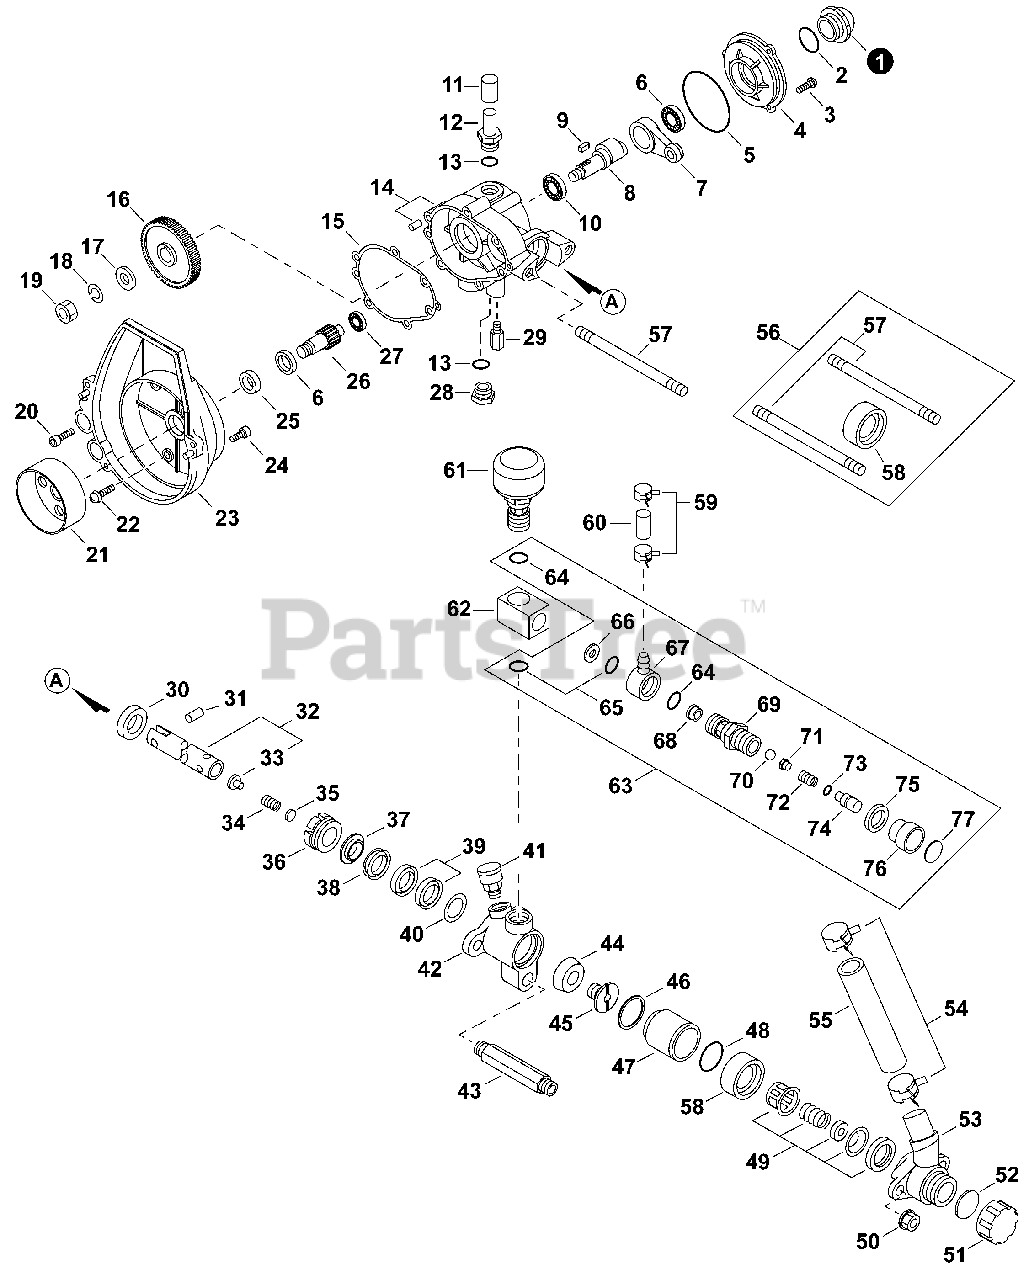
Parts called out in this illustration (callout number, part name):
1	GAUGE, OIL
3	SCREW 4x12
4	COVER, PUMP
6	BEARING, BALL 6001
7	ROD, CONNECTING
8	CRANKSHAFT
10	BEARING, BALL 6201
12	BOLT, OIL
14	CASE KIT, PUMP
15	GASKET, PUMP
16	GEAR, SPUR
17	WASHER 8.5x16x1.2
18	WASHER, SPRING 8
20	BOLT 5x25
21	DRUM, CLUTCH
22	SCREW 5x25
23	COVER, FAN
24	BOLT 5x18
25	SEAL, OIL
26	SHAFT, PINION
27	BEARING, BALL 609
28	CAP, DRAIN
30	SEAL, OIL
31	PIN, PISTON
32	PLUNGER SET, W/SPRING HOLDER
33	HOLDER, SPRING
34	SPRING, VALVE
38	PACKING, GREASE
39	PACKING SET
41	CUP ASSY, GREASE
42	CYLINDER
43	CONNECTOR, HOSE
44	PACKING, PISTON
45	SEAT, VALVE
49	VALVE ASSY
51	CAP, DRAIN
52	GASKET, DRAIN
53	PIPE, INTAKE
55	HOSE, INLET
56	CASING SET, VALVE
57	BOLT, STUD
58	CASING, VALVE
59	CLIP 10.5 MM
60	HOSE, RETURN
61	CHAMBER, AIR
62	CONNECTOR
63	REGULATOR ASSY
64	O-RING 12.5
65	O-RING 16 MM
67	CASING, VALVE
68	SEAT, VALVE
69	CASING, SPRING
70	BALL, PRESSURE STEEL
71	HOLDER, SPRING
72	SPRING, PRESSURE
73	O-RING 7 MM
74	SHAFT, REGULATOR
75	NUT, LOCK
76	CAP, REGULATOR
77	LABEL - REGULATOR
